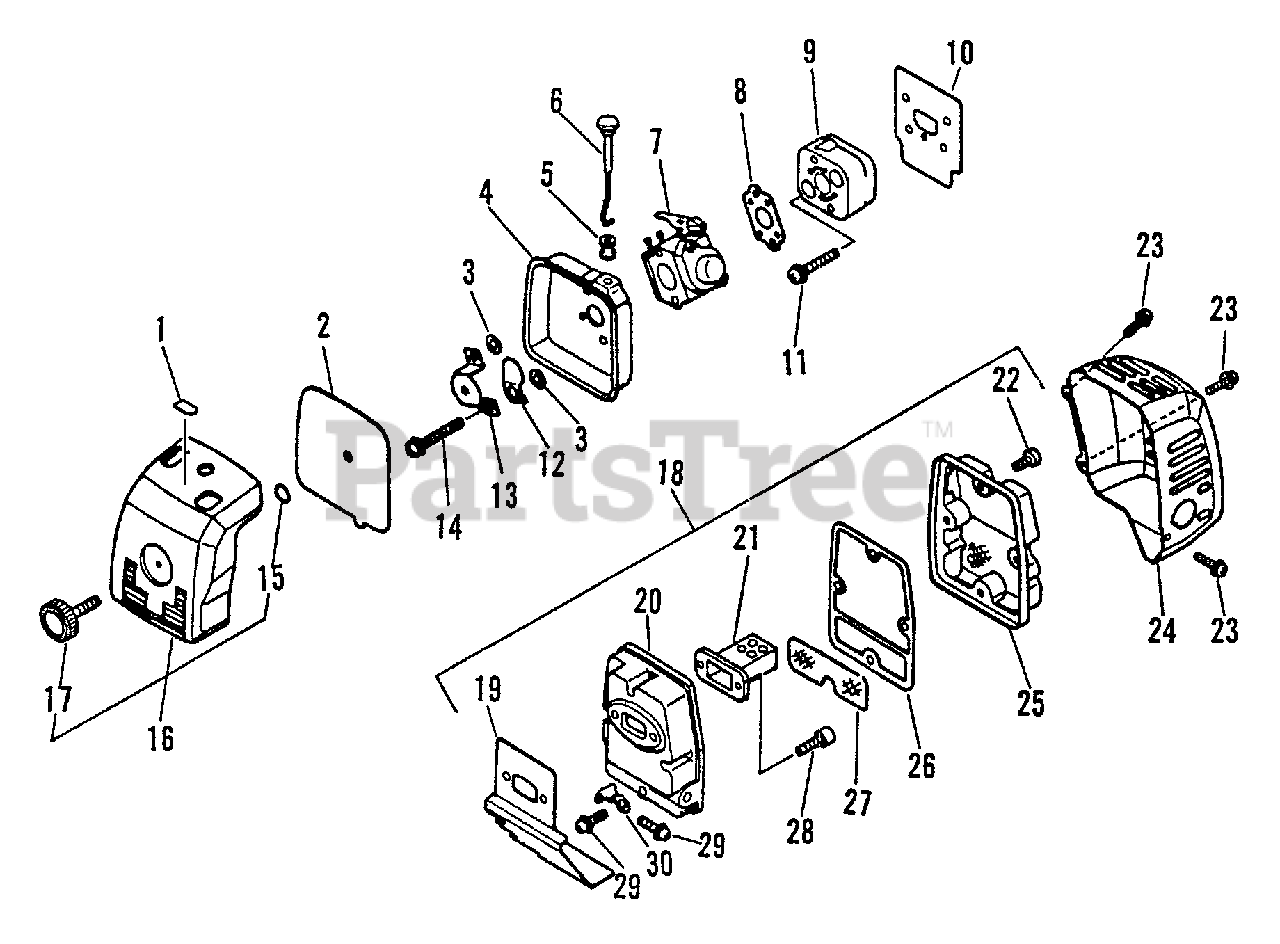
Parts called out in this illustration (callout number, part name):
1	LABEL - CHOKE
2	FILTER, AIR
3	WASHER 5.2×8×0.8T
4	CASE, AIR FILTER
5	GROMMET, CHOKE
6	ROD, CHOKE
7	CARBURETOR - C1U-K20
8	GASKET, INTAKE
9	INSULATOR
10	GASKET
11	SCREW 5×25
12	SHUTTER, CHOKE
13	PLATE, PREVENT
14	SCREW 5×50
15	O-RING 3
16	AIR FILTER COVER ASSY
17	THUMBSCREW
18	MUFFLER ASSY
19	GASKET, MUFFLER
21	SILENCER
22	BOLT 5×14
23	SCREW 4×8
24	COVER, MUFFLER
25	COVER, MUFFLER
26	GASKET, EXHAUST
27	SCREEN, SPARK ARRESTER
28	BOLT M5×18
29	SCREW 5×10
30	BRACKET, MUFFLER
